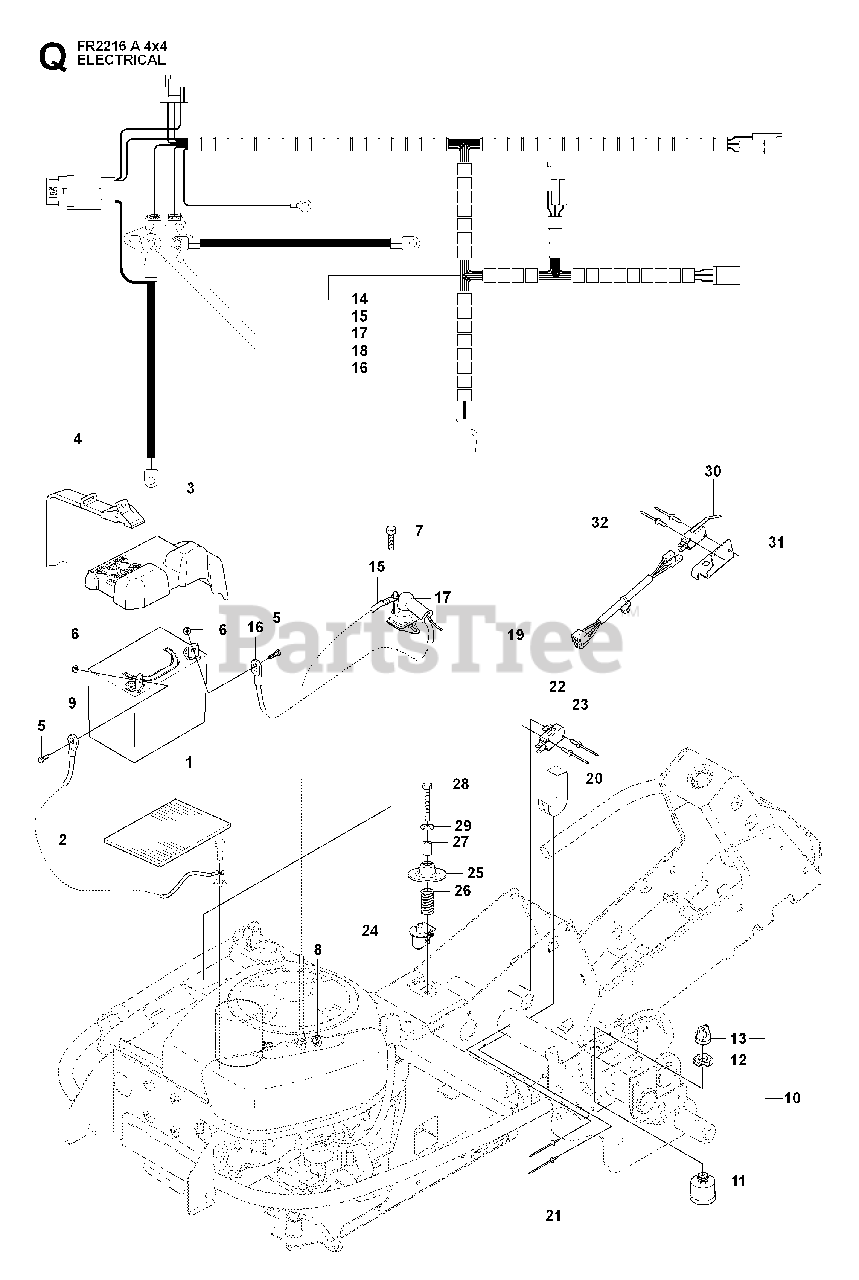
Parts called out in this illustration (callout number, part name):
5	SCREW EHHM
10	IGNITION SWITCH
11	IGNITION SWITCH
13	IGNITION KEY
22	%BRAKER
27	SPACER TUBE
28	SCREW
29	WASHER BRB 8.4X17
30	RP MICRO SWITCH
